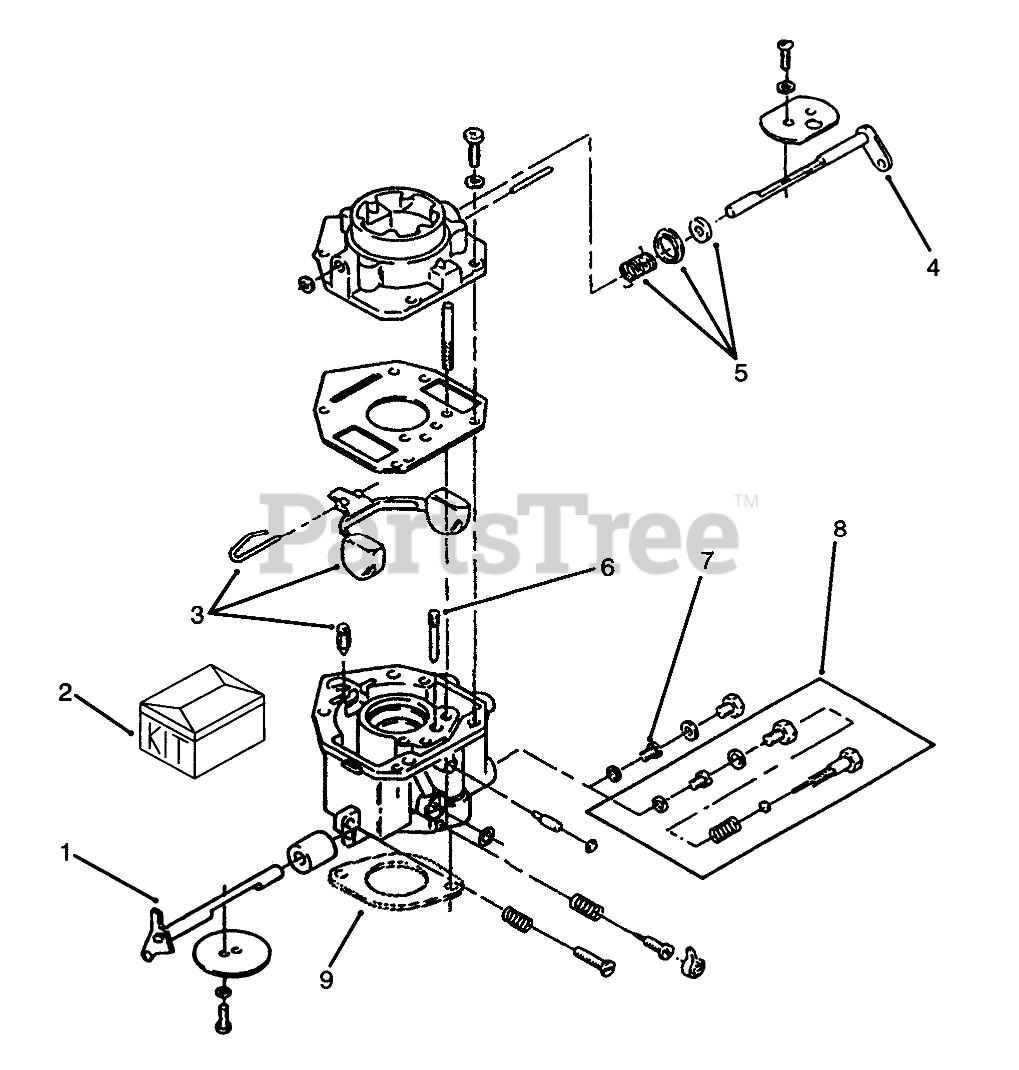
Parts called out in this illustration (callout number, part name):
1	Kit-Shaft, Throttle (Includes Valve Setscrew, Air Filter, & Throttle Valve)
2	Kit-Repair (Includes Screw & Plug Package, Gasket Package, Float Valve, Idle Adj. Needle & Spring, Mounting Gaskets, & Idle Limit Cap)
3	Kit-Float (Includes Float, Pin & Valve)
4	Kit-Shaft, Choke (Incl. Choke Valve, Valve Setscrew, & Air Filter)
5	Kit-Lever, Choke (Incl. Choke Lever Ring, Choke Spring, & Choke Collar)
6	IDLE-JET
7	POWER JET
8	FIXED-JET
9	Gasket
